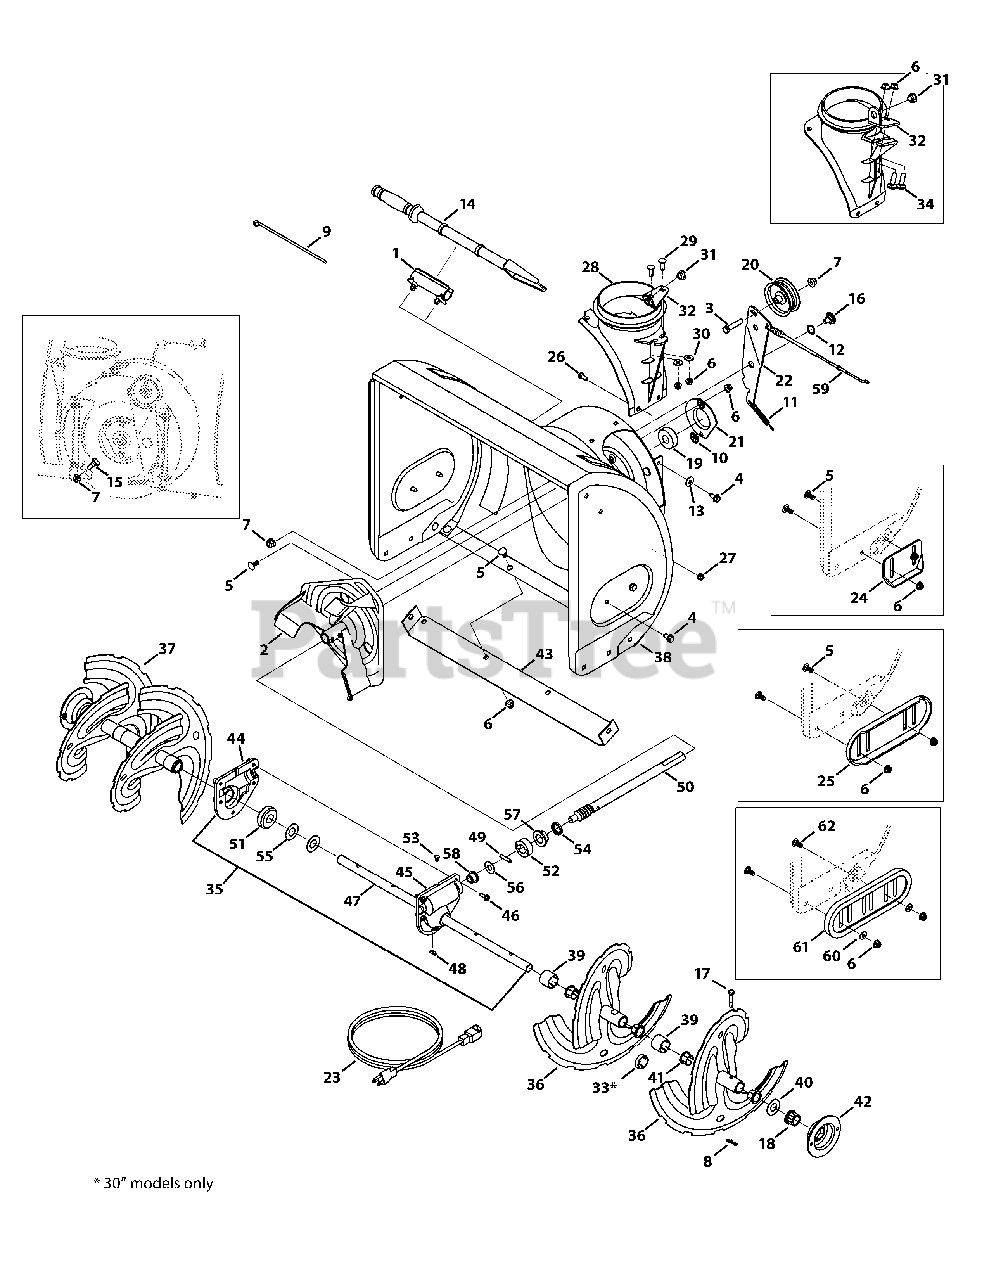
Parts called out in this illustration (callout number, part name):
1	Cleanout Tool Mount
2	Impeller Assembly, 12"
3	Hex Screw, 3/8-16 x 1.75
4	Hex Washer Screw, 5/16-18 x .750
5	Carriage Bolt, 5/16-18 x .750
6	Flange Lock Nut, 5/16-18
7	Flange Lock Nut, 3/8-16
8	Bow-Tie Cotter Pin
9	Cable Tie, 3/16 x .05 x 7.4
10	Push Nut, .25 Dia.
11	Extension Spring
12	Wave Washer, .625 x .885 x .015
13	Bell Washer, .340 x .872 x .060
14	Chute Cleanout Tool
15	Shoulder Bolt, .496 x .336 x 3/8-16
16	Shoulder Screw, .625 x .17 x 3/8-16
17	Shear Pin, .25 x 1.50
18	Hex Flange Bearing, .75 ID
19	Ball Bearing, .75 ID x 1.85 OD
20	Idler Pulley, 2.75 OD
21	Bearing Housing, 1.85 ID
22	Auger Idler Bracket
23	Extension Cord (Electric Start Only)
24	Skid Shoe
25	Deluxe Skid Shoe - Red
25	Deluxe Skid Shoe - Black Jack
25	Deluxe Skid Shoe - Green
26	Carriage Screw, 1/4-20 x .75
27	Flange Lock Nut, 1/4-20
28	Chute Adapter, 5"
28	Chute Adapter, 5" (4-way)
28	Chute Adapter, 5" (side crank)
29	Carriage Screw, 5/16-18 x 1.00
30	Flat Washer, .349 x .879 x .063
31	Plastic Bushing, .380 ID
32	Chute Crank Bracket
33	Spacer, 1.250 x .75 ID x 3/16 LG*
34	Carriage Bolt, 5/16-18 x 1.00
35	Gearbox Assembly, 22"
35	Gearbox Assembly, 24"
35	Gearbox Assembly, 26"
35	Gearbox Assembly, 28"
35	Gearbox Assembly, 30"
36	Spiral Assembly, LH - Black
36	Spiral Assembly, LH - Grey
37	Spiral Assembly, RH - Black
37	Spiral Assembly, RH - Grey
38	Auger Housing Assembly, 22" Red
38	Auger Housing Assembly, 24" Red
38	Auger Housing Assembly, 24" Black
38	Auger Housing Assembly, 24" Green
38	Auger Housing Assembly, 26" Red
38	Auger Housing Assembly, 26" Black
38	Auger Housing Assembly, 26" Green
38	Auger Housing Assembly, 28" Red
38	Auger Housing Assembly, 28" Black
38	Auger Housing Assembly, 28" Green
38	Auger Housing Assembly, 30" Red
38	Auger Housing Assembly, 30" Black
39	Spacer, 1.2500 x .75 ID x 1.00
40	Flat Washer, .76 x 1.49 x .06
41	Flange Bushing, .800 ID x .910 OD
43	Shave Plate, 22" Red
43	Shave Plate, 24" Red
43	Shave Plate, 24" Black
43	Shave Plate, 24" Green
43	Shave Plate, 26" Red
43	Shave Plate, 26" Black
43	Shave Plate, 26" Green
43	Shave Plate, 28" Red
43	Shave Plate, 28" Black
43	Shave Plate, 28" Green
43	Shave Plate, 30" Red
43	Shave Plate, 30" Black
44	Housing Assembly, RH
45	Housing Assembly, LH
46	Hex Washer Screw, 1/4-20 x .750
47	Auger Axle, 22"
47	Auger Axle, 24"
47	Auger Axle, 26"
47	Auger Axle, 28"
47	Auger Axle, 30"
48	Hi-Pro Key
49	Dowel Pin, .25 OD x 1.25 LG
50	Worm Shaft, .75 OD
51	Worm Gear 20 T, 24" & 26"
51	Worm Gear 20 T, 28"& 30"
52	Thrust Collar, .756 ID x .600
53	Plug, 1/4 x .437
54	Oil Seal, .75 x 1.131 x .188
55	Flat Washer, .760 ID x 1.50 ID
56	Flat Washer, .51 x 1.12 x .06
57	Flange Bearing, .75 ID x 1.0 OD x .59
58	Flange Bearing, .50 ID x .75 OD x .59
59	Auger Drive Cable
60	Washer, Flat, .349 x .879
61	Slide Shoe, Poly Deluxe
61	Deluxe Polymer Reversible Shoe Kit
62	Carriage Screw, 5/16-18 x 1.00
